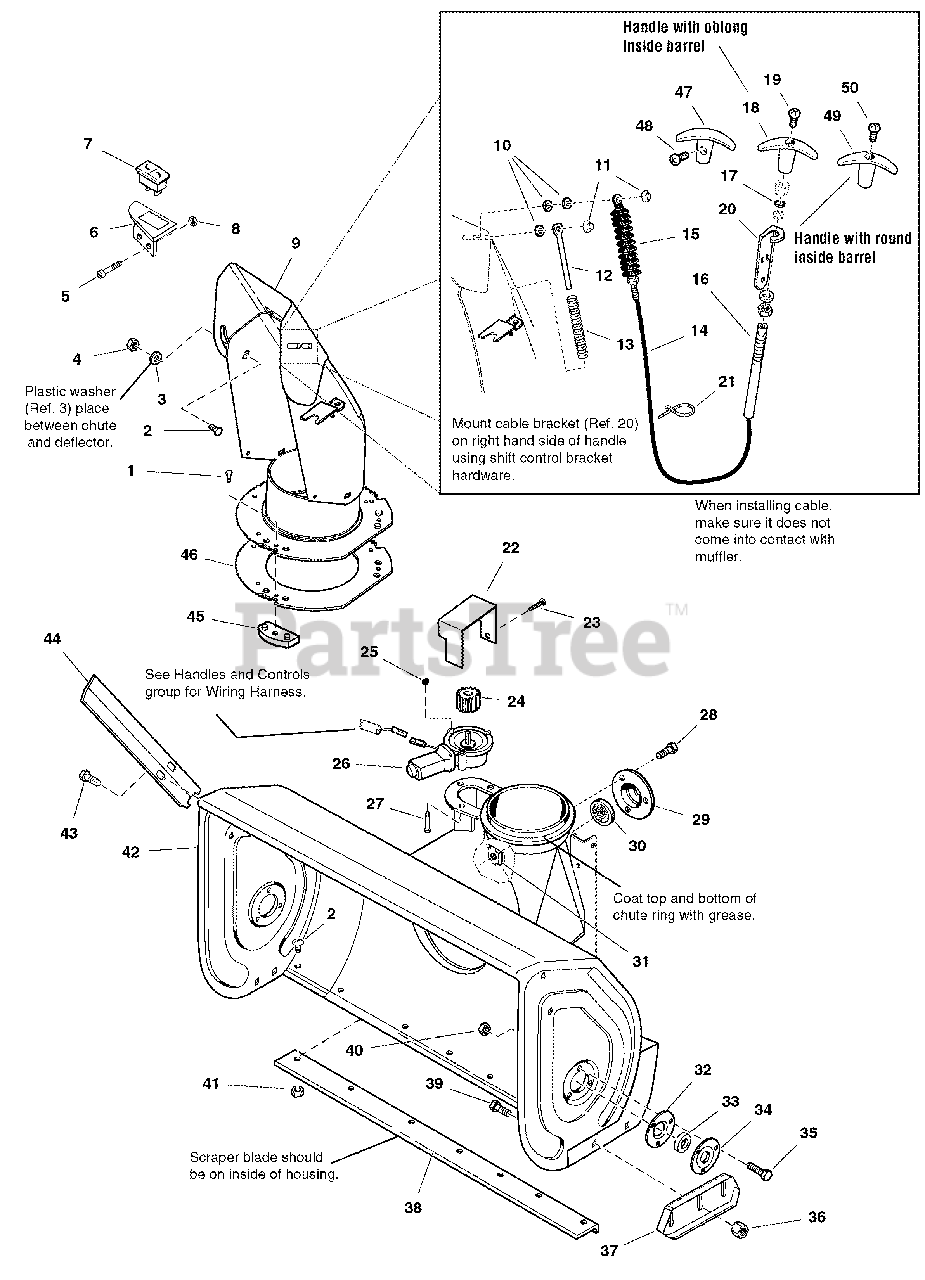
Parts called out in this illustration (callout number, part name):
1	SCREW, Hex Washer Head Pastite, 10-14 x 5/8
2	CARRIAGE BOLT, 5/16-18 x 3/4 G5
3	WASHER, Special, 97/250ID x 1-3/25OD x 3/100 Thick
4	NUT, Hex Falnge ESNA, 5/16-18
5	SCREW, Hex Whiz Lock, 1/4-20 x 3/4
6	BRACKET, Mounting Switch
7	SWITCH, Rocker Chute
8	NUT, Hex Nylon 10-24
9	CHUTE AND DEFLECTOR ASSEMBLY
10	SPACER, Heat Treated
11	NUT, Push Pal, 1/4" Diameter Stud Capped
12	ROD, 5/16" Diameter, Spring Guide
13	SPRING, Complete
14	CABLE AND KNOB ASSEMBLY, Chute (Includes Ref. No. 18, 19, 20, 21 & 22)
15	BOOT, Bellows
16	COLLET
17	SEAL, Rod
18	KNOB
19	SCREW, 8-32
20	SUPPORT, Cable
21	TIE, Self Locking
22	COVER, Pinion, 18GA
23	CAPSCREW, Hex Washer Head Taptite, 1/4-20 x 1/2
24	PINION, 1-3/20 LG
25	NUT, Hex KEPS, #10-24
26	MOTOR, Electric
27	SCREW, Hex Washer Head Slot, #10-24 x 1-1/4
28	CAPSCREW, Hex Head Whiz Lock, 5/16-18 x 3/4
29	RETAINER, Bearing
30	BEARING, Ball
31	NUT, Retainer Speed, 5/16-18
32	FLANGE, Bearing, w/Fitting
33	BEARING, Cartridge
34	FLANGE, Bearing, 3/8" Deep
35	CAPSCREW, Hex head, 5/16-18 x 5/8
36	NUT, Hex Flange, 3/8-16 ESNA
37	SKID SHOE, 7GA Formed, Heat Treated
38	BLADE, Scraper, 35-3/4 for 38"
39	CARRIAGE BOLT, 3/8-16 x 1 G5
40	NUT, Hex Flange Whiz Lock, 5/16-18
41	NUT, Flange Lock, 5/16-18
42	HOUSING AND IMPELLER ASSEMBLY, 38"
43	CAPSCREW, Hex Washer Head Taptite, 5/16-18 x 3/4 G5
44	CUTTER, Drift, Red
45	HOLD DOWN, Chute
46	GEAR, Chute
48	SCREW, Set, Hex #10-24 x 3/8
49	HANDLE "T"
50	SCREW, Round Head
